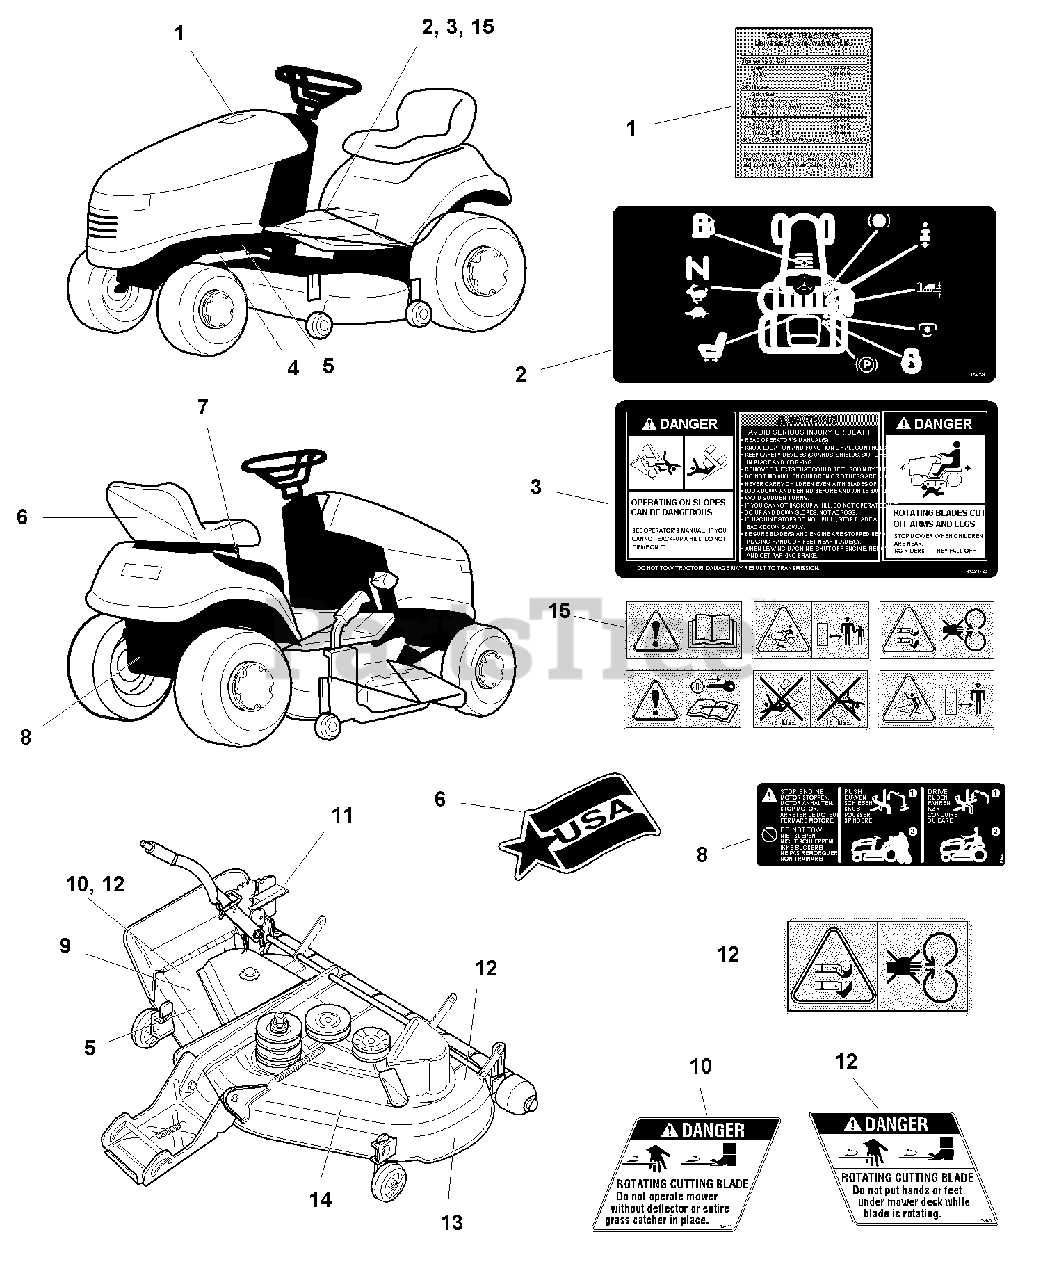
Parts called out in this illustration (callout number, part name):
1	DECAL, Belts & Mower Blades
2	DECAL, Operating Instructions
3	DECAL, Safety Instructions
4	DECAL - Patent
5	DECAL, Serial Number (Not Serviced)
5	DECAL, CE & Serial Number Export (Not Serviced)
7	DECAL, PTO Control Symbols
8	DECAL, Transmission Relese Valve, Hydros only
10	DECAL, Danger
11	DECAL, Height of Cut
12	DECAL, Danger
12	DECAL, Danger Symbol
13	DECAL, Free Floating Mower
14	DECAL, OPEI (Not Serviced)
15	DECAL, Tunnel, Export
